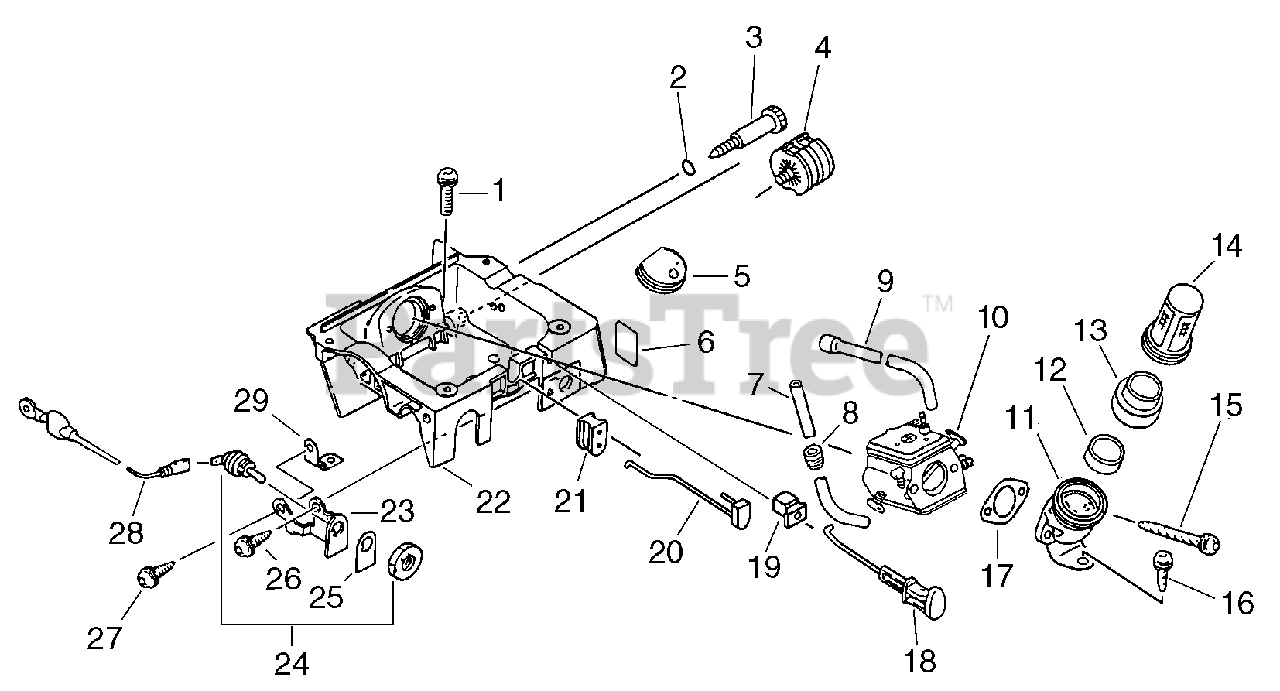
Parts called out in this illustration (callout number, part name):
1	SCREW - 5X20
2	O-RING - 7
3	SCREW, IDLE ADJUST
5	GROMMET
6	LABEL - IDLE
7	PIPE - 3X6X130
8	GROMMET
9	PIPE - IMPULSE
10	CARBURETOR HDA-216
11	ADAPTOR, INTAKE
12	COLLAR - 22
13	CUSHION
14	SCREEN, DEBRIS
15	SCREW - 5X53
16	SCREW - 5X14
17	GASKET, INTAKE
18	ROD, CHOKE
20	ROD, THROTTLE
21	GUIDE, THROTTLE ROD
22	CASE, CARBURETOR
23	BRACKET, SWITCH
24	IGNITION SWITCH ASSY
25	LABEL - SWITCH
26	SCREW - 5X10
27	SCREW - 4X10
28	LEAD - GROUND
29	TERMINAL - GROUND
